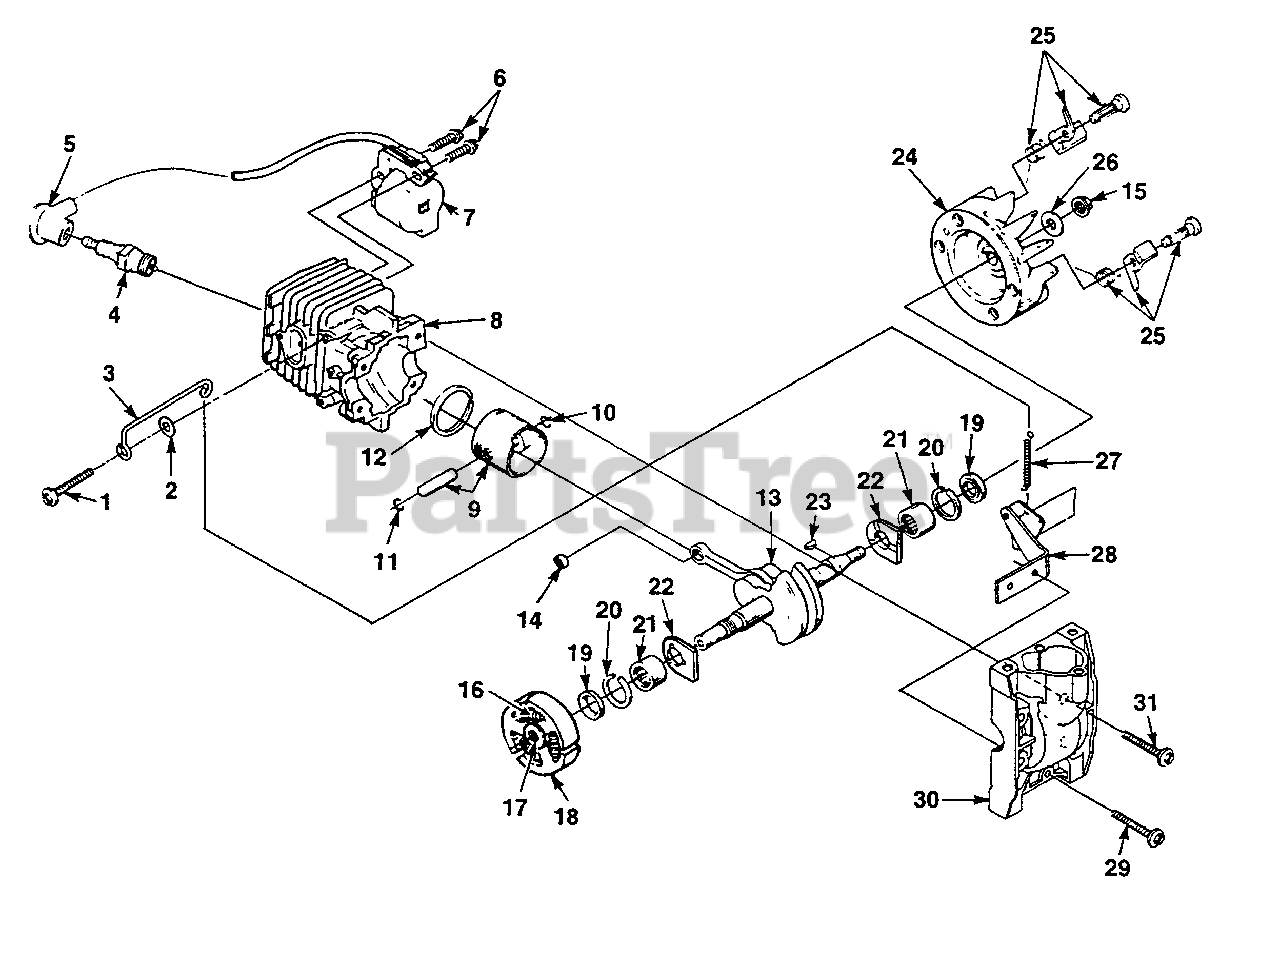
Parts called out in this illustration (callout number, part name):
1	SCREW-Hex Washer Hd. (10-24 x 1/2")
2	WASHER-Flat
3	BRACKET-Spring
4	SPARK PLUG (RDJ-7Y)
5	TERMINAL-Spark Plug
6	SCREW-Thd. Form (8-32 x 1)
7	MODULE-Ignition
8	CYLINDER
9	PISTON & PIN ASSEMBLY
10	RING-Retaining
11	RING-Retaining
12	RING-Piston
13	CRANKSHAFT
14	BEARING-Needle
15	NUT-Lock
16	SPRING-Clutch
17	SPIDER-Clutch
18	SHOE-Clutch
19	SEAL-Shaft
20	SPACER-Seal
21	BEARING-Needle
22	WASHER-Thrust
23	KEY-Woodruff
24	ROTOR & PAWL ASSEMBLY
25	STARTER PAWL KIT
26	WASHER-Flat
27	SPRING-Governor
28	AIR VANE & BRACKET ASSY.
29	SCREW-Thd. Rolling
30	CRANKCASE
31	SCREW-Truss Hd. (10-24)
